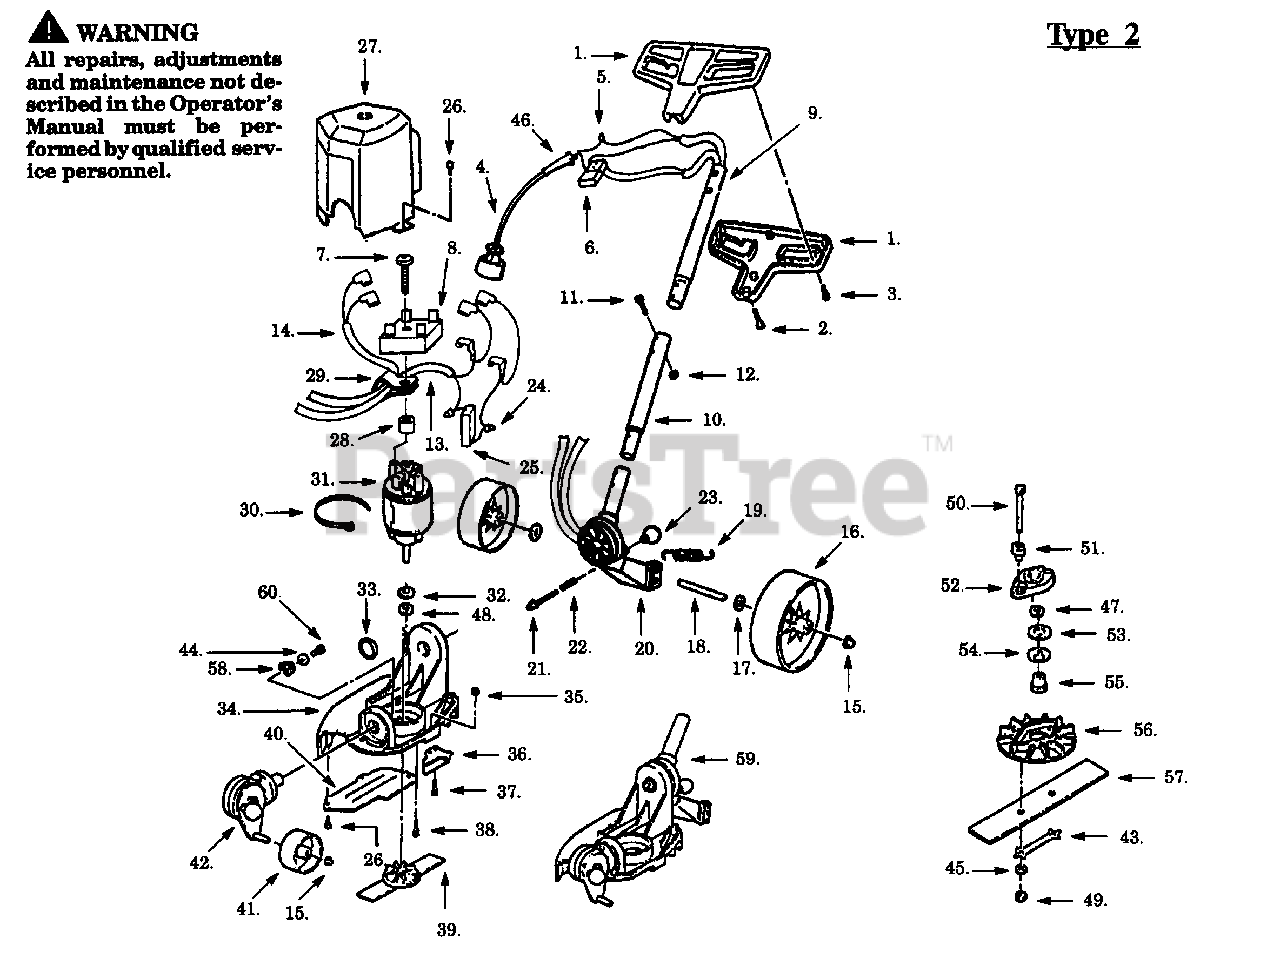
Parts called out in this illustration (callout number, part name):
1	Handle Set
4	Power Cord
5	Wire Nut
9	Upper Tube
10	Lower Tube
13	Harness Ass'y. (Red/White)
14	Harness Ass'y. (Blue/White)
15	Push Nut
16	Rear Wheel
18	Rear Axle
20	Rear Swivel
21	Pin-Index
22	Swivel Lock Spring
24	Terminal Cap
25	Resister
27	Motor Cover
30	Tie Wrap
31	Motor Ass'y., E125BT
31	Motor Ass'y., E150BT
33	Retaining Ring
34	Deck Frame
36	Blade Guide
39	Blade Ass'y.
40	Side Guard Plate
41	Front Wheel
42	Front Swivel Ass'y
43	Lock Strap
45	Lockwasher
51	Insulating Sleeve
52	Clutch Plate
54	Spring Washer
55	Clutch Sleeve
58	Front Swivel Spring
59	Frame Ass'y
